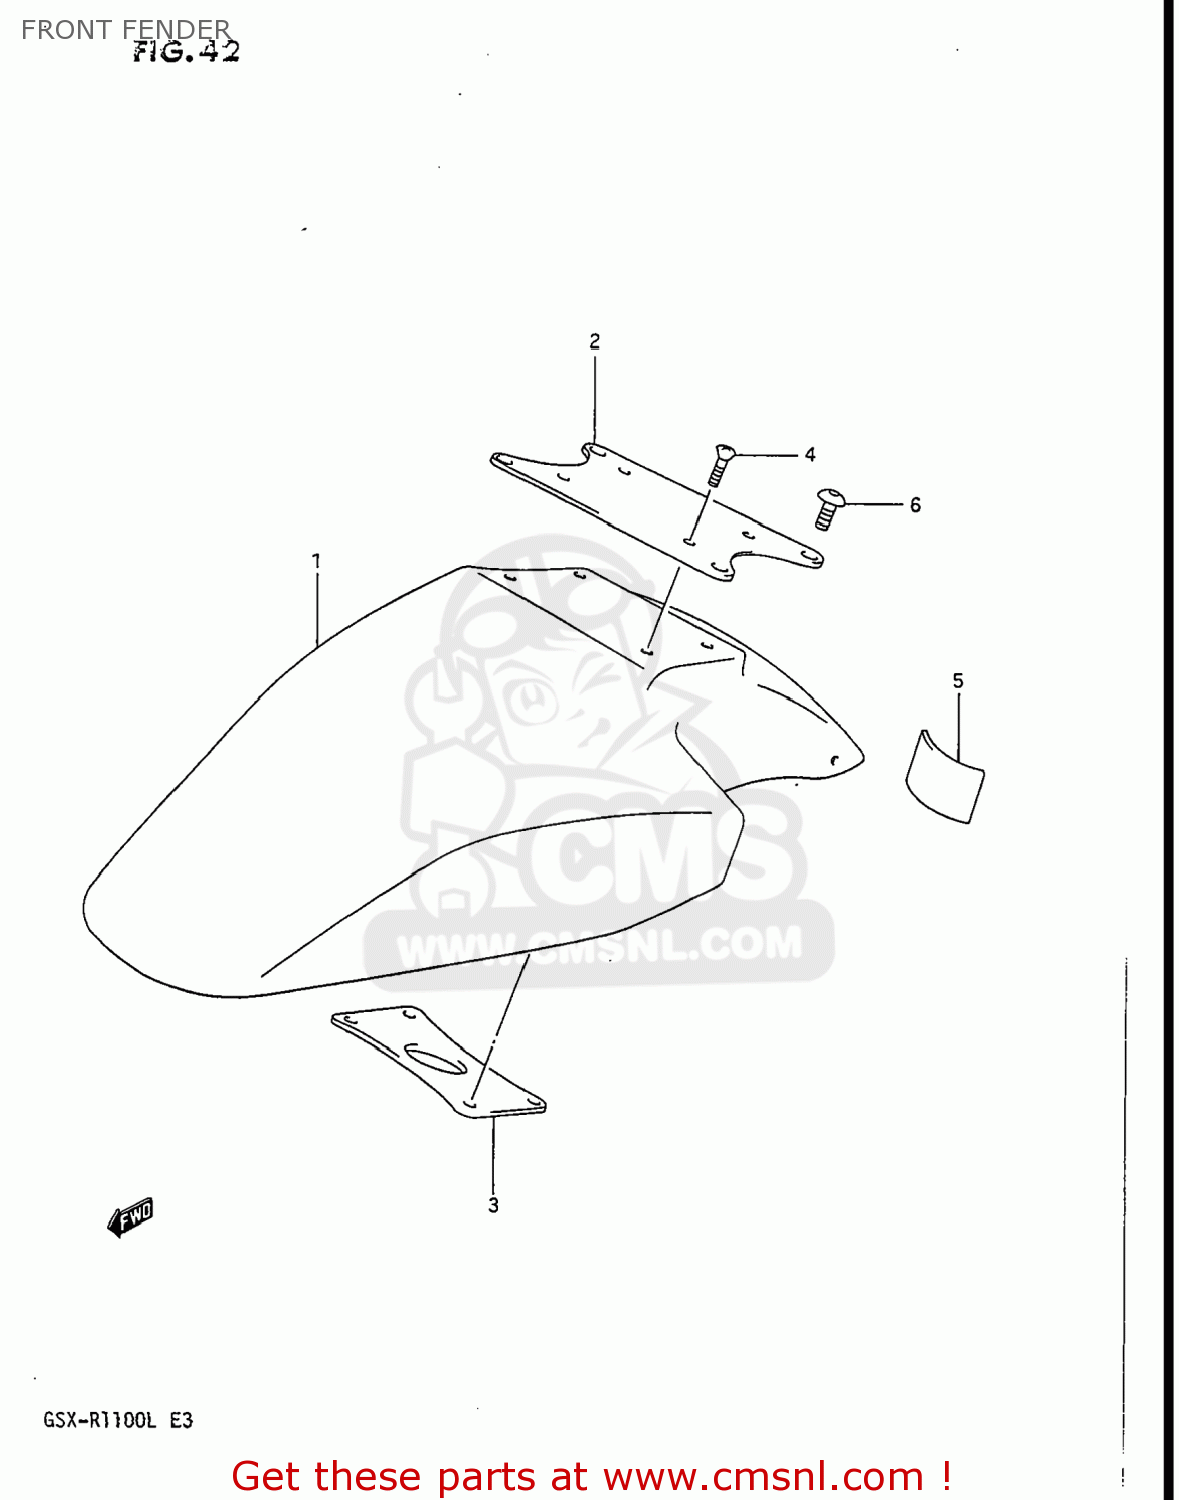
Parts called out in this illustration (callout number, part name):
1	FENDER,FRONT
2	BRACE,FR FENDER
3	BRACE,FR FENDER INNER
4	SCREW(5X18)
5	CUSHION,FR FENDER
6	SCREW(8X16)
